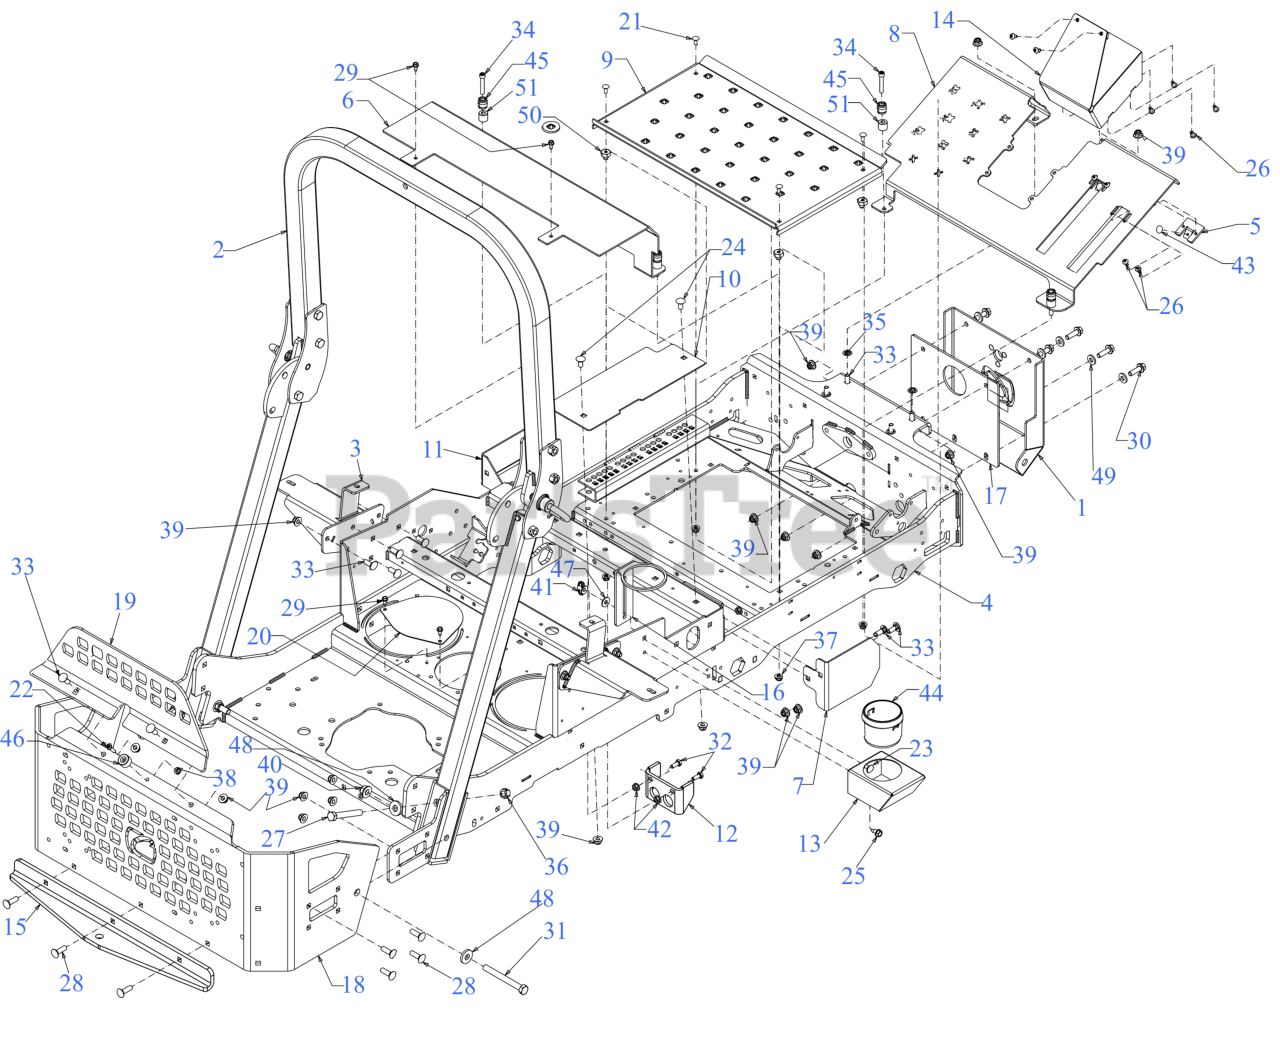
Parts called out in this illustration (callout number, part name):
2	PRO Z ROPS KIT
3	FUEL TANK MOUNT
4	FRAME
5	REVERSE PEDAL STOP BRACKET
11	SEAT BOX END COVER (LH)
17	FRONT MOUNTING PLATE SPACER
18	BUMPER (LOWER RR)
19	BUMPER (UPPER RR)
20	FRAME COVER PLATE
21	CARRIAGE BOLT 1/4-20 x .62
22	MACHINE SCREW 1/4-20:1
23	CARRIAGE BOLT 5/16-18 x 1.00
24	CARRIAGE BOLT 3/8-16 x .750 GR5
25	SCREW 5/16-18 x .750
26	SCREW 1/4-20 x .5
27	SCREW 1/2-20 x 3.50 GR5
28	CARRIAGE BOLT 3/8-16 X1.25 GR5
29	SCREW 1/4-20 X.500
30	SCREW 3/8-16 x 1.25 GR5
31	SCREW 1/2-13 x 4.5 GR 5
32	SCREW 5/16-18 x .75 GR5
33	CARRIAGE BOLT 3/8-16 x 1.00 GR5
34	SCREW 5/16-18X1.75 GR5
37	FLANGE LOCK NUT 5/16-18
38	FLANGE LOCK NUT
41	WING NUT 5/16-18
42	FLANGE NUT
43	RATCHET CLIP
45	RADIAL BUMPER
47	FLAT WASHER
48	FLAT WASHER .531 x 1.25 x .181
49	FLAT WASHER
50	SHOULDER SPACER
